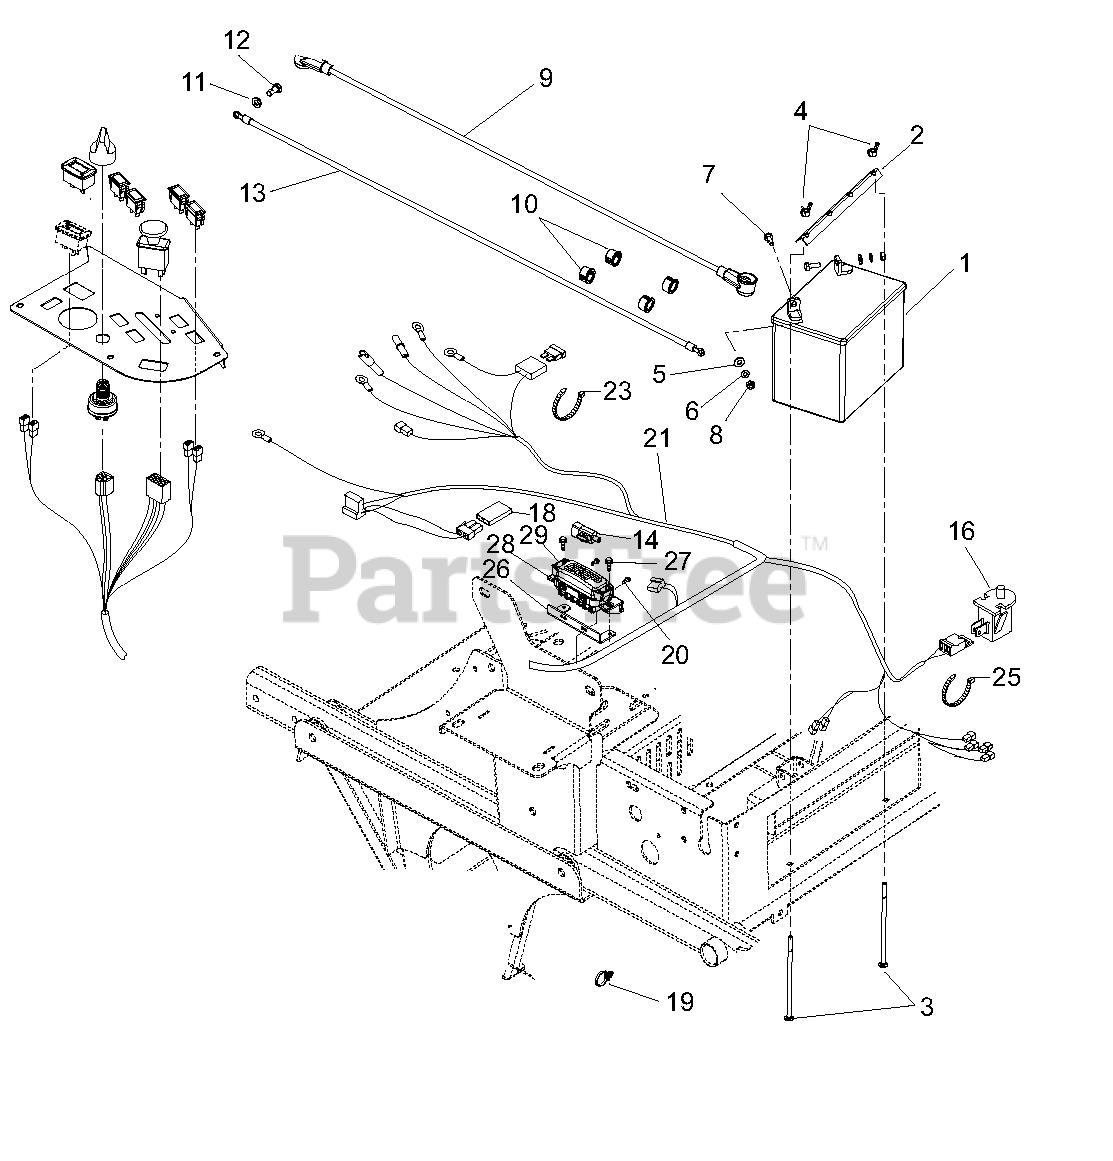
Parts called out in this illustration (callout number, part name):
1	Battery, Group 70-540 CCA
2	Hold Down
3	Bolt, Round Heard Square Neck .25-20 x 7.50
4	Nut, Locking Wing .250-20
5	Washer, Flat-Steel .281 x .62 x .065
6	Washer, Locking .25 x .062 Regular
7	Bolt, Hex .25-20 x .75 Grade 5
8	Nut, Hex .25-20
9	Cable, POS Batter w/Boots 6 x 35
10	Bushing, Panel Snap .687 x .875 x .56
11	Washer, Locking .31 x .078 Regular
12	Bolt, Hex M8-1.25 x 20
13	Cable, Negative Battery 35.0"
14	Switch, Snap-In - N.O./N.O.
16	Switch, Snap Mounting (Included with Seat)
17	Fuse, 30 Amp (Included with Harness)
18	Diode, Connector Shell (Included with Harness)
19	Cable Tie with TREE (.25 HOLE)
20	Bolt, Hex M6-1.0X25
21	Harness, PT400 Wiring
23	Cable Tie
24	Lead, Starter Solenoid
25	Cable Tie
26	Fuse Holder Mounting Bracket
27	Screw-Tapping .25-20x.50 Hex Washer Head
28	Fuse Holder (included with Harness)
29	Cover, Fuse Holder
